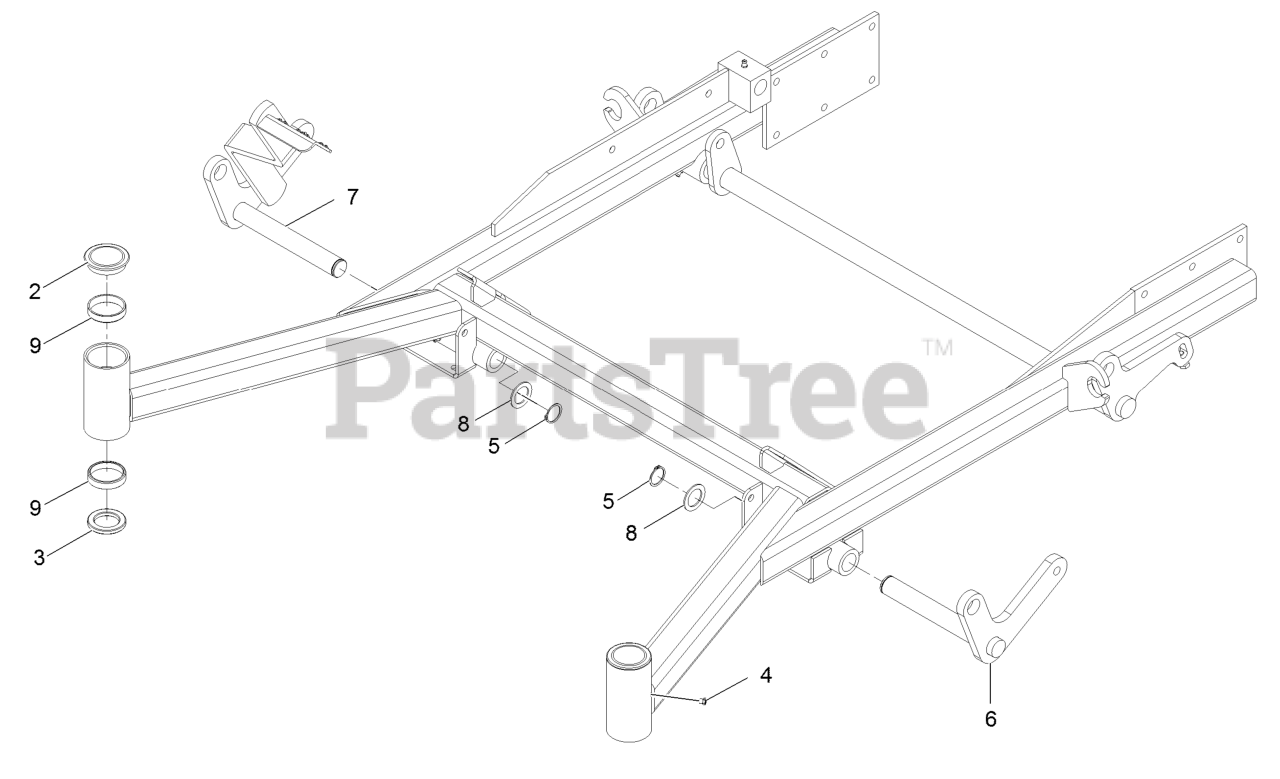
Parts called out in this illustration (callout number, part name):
2	CAP-GREASE
3	SEAL-GREASE
5	RING-RETAINING
6	WLD,FRONT LIFT SHAFT-LH
7	WLD,FRONT LIFT W/LEVER
8	WASHER-SPACER
9	CUP-BEARING
